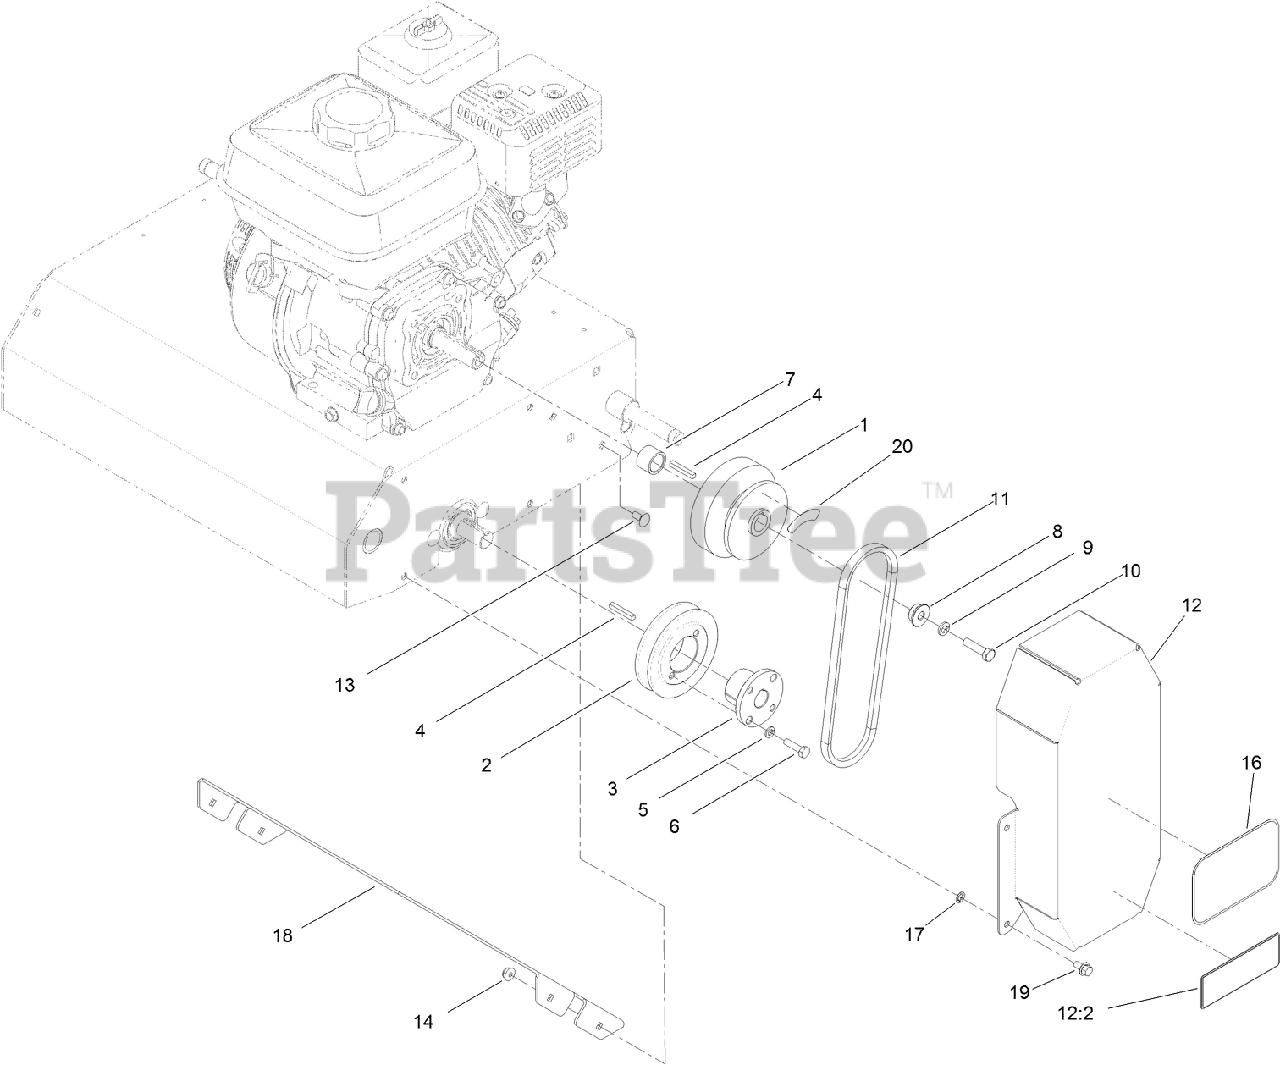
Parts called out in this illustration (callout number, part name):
1	CLUTCH-CENTRIFUGAL
2	SHEAVE-TAPER LOCK
3	BUSHING-TAPER LOCK
4	KEY-SQUARE
5	WASHER-LOCK
6	SCREW-HH
7	SPACER
8	BUSHING
9	WASHER-LOCK
10	SCREW-HH
11	V-BELT
12	BELT GUARD ASM
12:2	DECAL-DANGER
13	SCREW-CARR
14	NUT-HF
16	DECAL
17	NUT-RETAINING
18	BAFFLE-DEFLECTOR
19	SCREW-HHF
20	DECAL-WARNING
